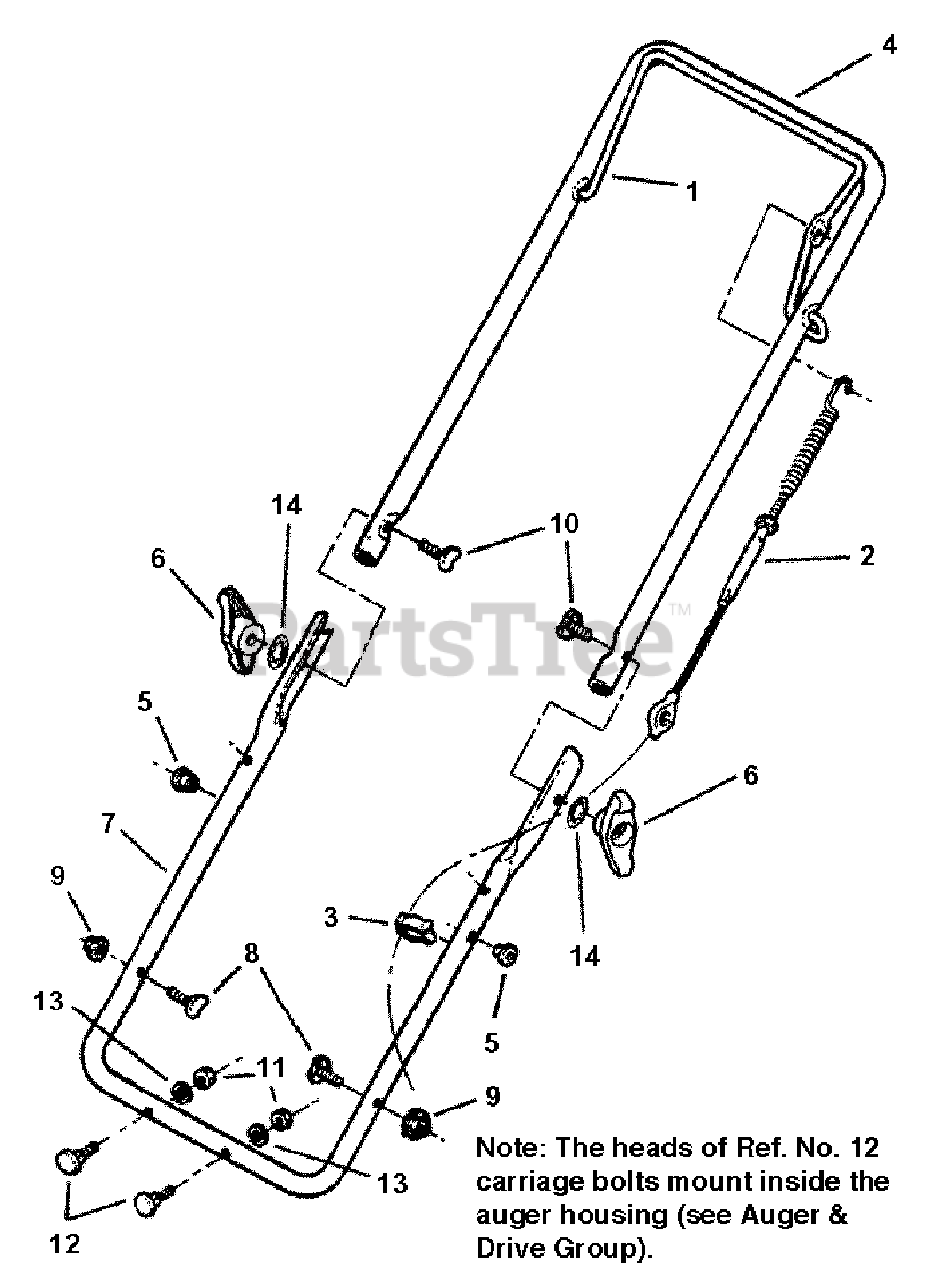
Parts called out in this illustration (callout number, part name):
1	BAIL, Drive Control
2	CABLE, Drive Control
3	CLIP, Wiring Harness
4	HANDLE, Upper
5	INSERT, Nylon
6	KNOB, 5/16-18 Wing, Black
7	HANDLE, Lower
8	BOLT, 5/16-18 x 1-3/8" Curved Head
9	NUT, 5/16-18 Hex Flange Lock, Grade 5
10	BOLT, 5/16-18 x 2" Curved Head, Grade 2
11	NUT, 5/16-18 Hex
12	CARRIAGE BOLT, 5/16-18 x 1-1/2, Grade 5
13	WASHER, 5/16 Split Lock
14	WASHER, 5/16 Internal Tooth Lock
